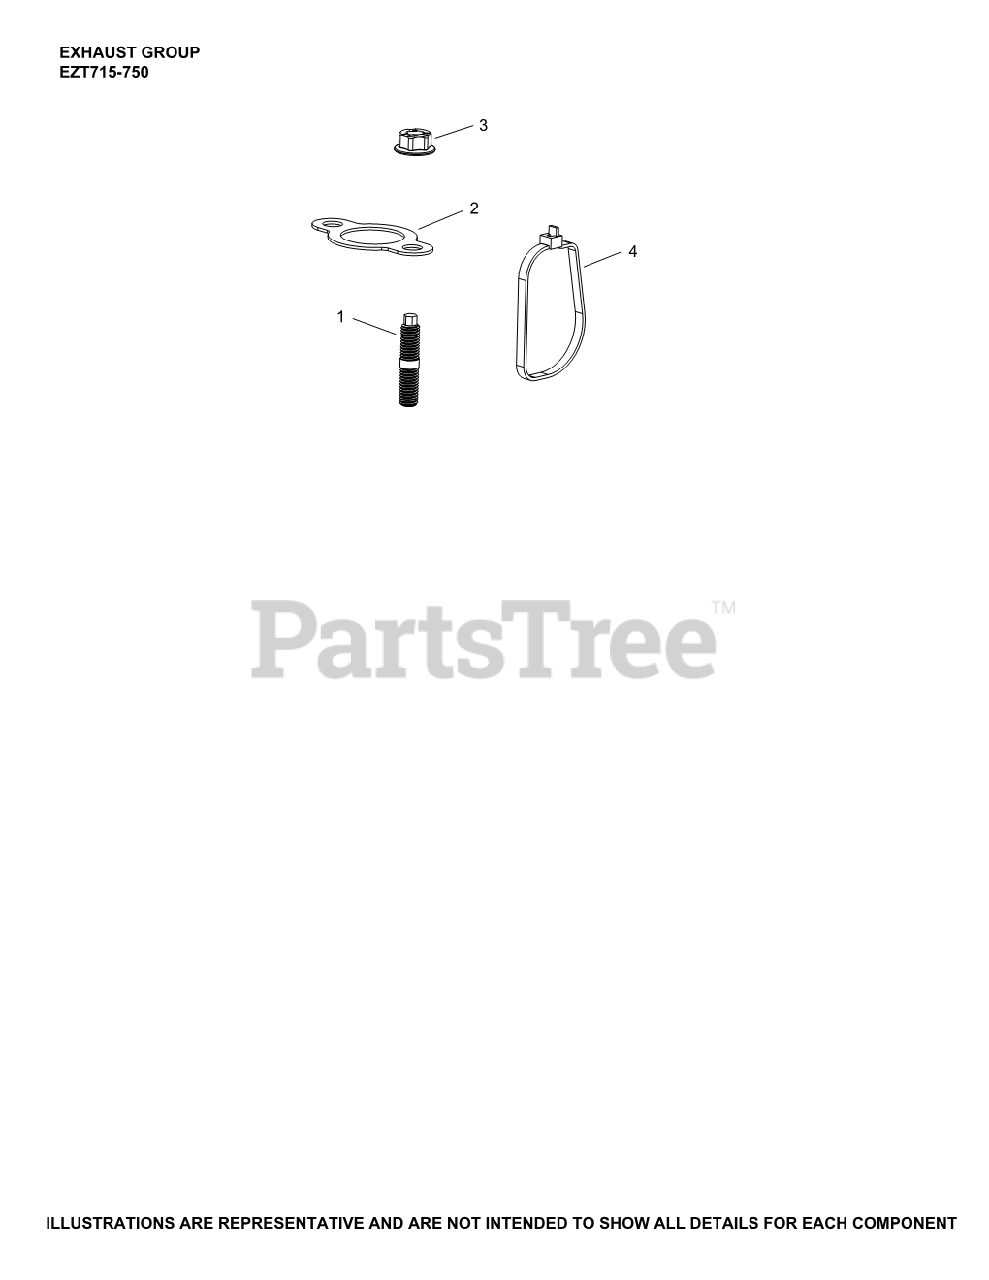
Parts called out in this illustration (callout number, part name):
1	STUD, EXHAUST USE 25 072 36-S
2	GASKET, EXHAUST
3	NUT, HEX FLANGE LOCK (M8)
